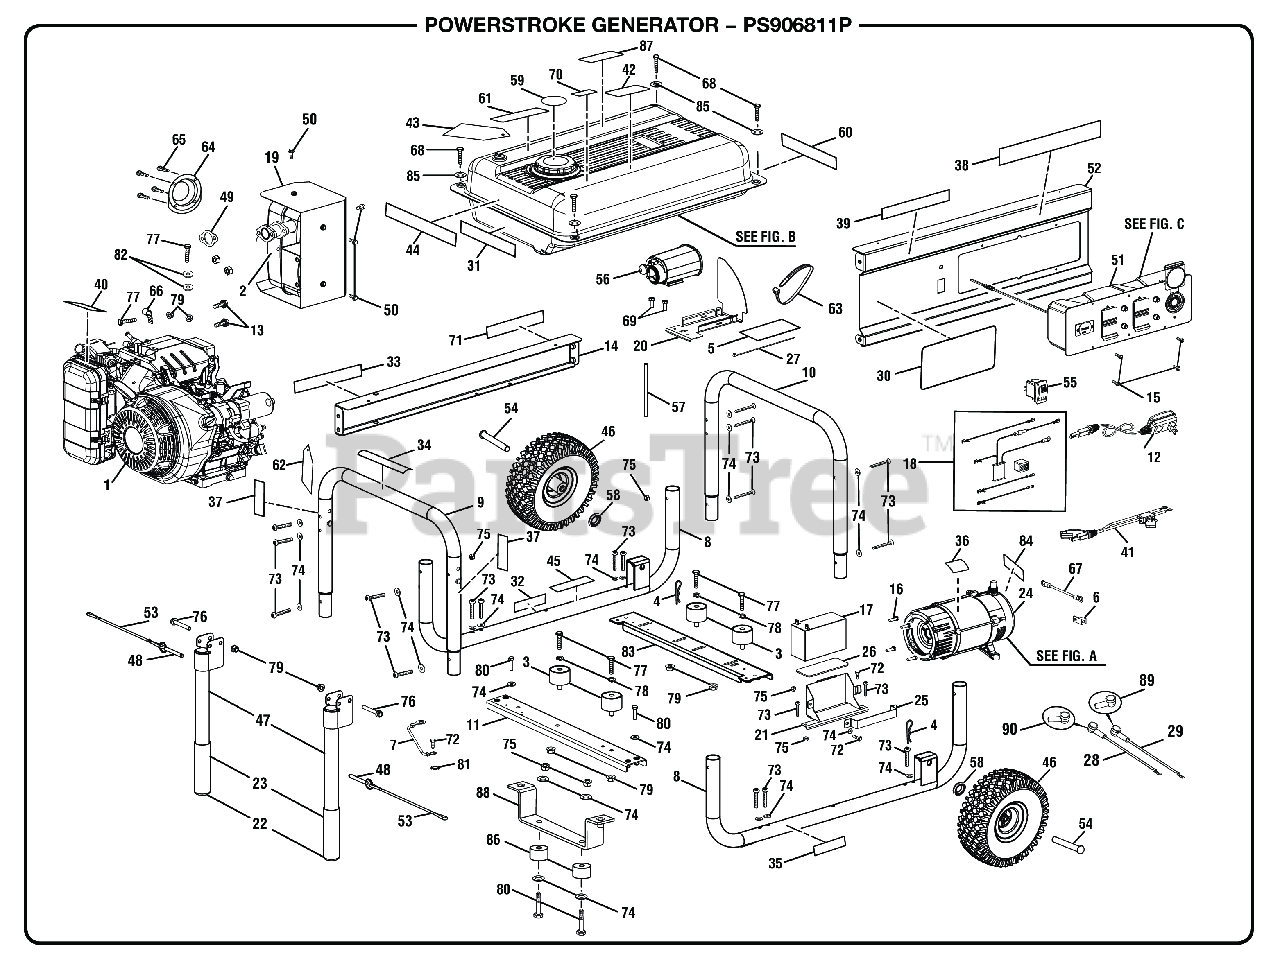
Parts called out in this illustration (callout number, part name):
1	Engine (Subaru EA190)
2	Muffler
4	Hitch Pin
5	Rubber Sheet
6	Ground Lug
7	Ground Wire Assembly
8	Lower Frame Assembly
9	Tube Assembly (Left)
10	Tube Assembly (Right)
11	Cross Brace (Engine)
12	Battery Charger
13	Bolt (5/16-24 x 5/8 in.)
14	Back Panel
15	Screw (6-20 x 3/8 in.)
16	Bolt (3/8-16 x1.25 in.)
17	Battery Bracket
18	Wire Harness
19	Heat Shield
20	Bracket (Carbon Canister)
21	Battery Box Gasket
23	Handle Grip
24	Generator Head w/AVR
25	Battery Hold Down Bracket
26	Gasket (Battery Hold Down Bracket)
28	Battery Cable (Red)
29	Battery Cable (Black)
30	Logo Label
31	Electric Start Label
32	Hot Surface Label
33	Danger Label
34	Fire Danger Label
35	Engine Lubricant Label
36	Data Plate Label
37	Locking Pin Label
38	Honda Label
39	Electric Start Label
40	Choke Label
41	Pigtail (DC)
42	Fuel Warning Label
43	Danger Hang Tag
44	Inquires Label
45	Combustion Warning Label
47	Handle Assembly
48	Release Pin (5/16 x 2 in.)
50	Bolt (M6 x 9 mm)
51	Panel Assembly
52	Front Panel
55	Start Switch w/Lock
56	Carbon Canister Assembly
57	Purge Hose
58	Washer (1/2 in.)
59	Fuel Stabilizer Label
60	Ground Warning Label
61	Fuel Stabilizer Label (Sp)
62	Hang Tag (Eng/Sp)
63	Cable Tie
64	Spark Arrestor
65	Screw (8-32 x 3/8 in., Pan Hd.)
66	J-Clamp (1/2 in.)
67	Bonding Wire
68	Screw (1/4-14 x 1-1/4 in.)
69	Screw (#10-16 x 3/4 in.)
70	E85 Label
71	Fire Distance Label
72	Screw (M6 x 16 mm, Hex Hd.)
73	Screw (M6 x 50 mm, T30, Pan Hd)
74	Washer (M6)
75	Lock Nut (M6)
76	Bolt (M8 x 55 mm, Hex Hd.)
77	Bolt (M8 x 35 mm, Hex Hd.)
78	Washer (M8)
79	Flange Nut (M8)
80	Bolt (M6 x 25 mm, Hex Hd.)
81	Star Washer (M6)
82	Washer (5/16 in)
83	Cross Brace (Generator Head)3
84	Ground Label
85	Washer (1/4 in.)
87	CPSC Label
88	Foot Bracket
89	Rubber Battery Cable Boot (Black)
90	Rubber Battery Cable Boot (Red)
